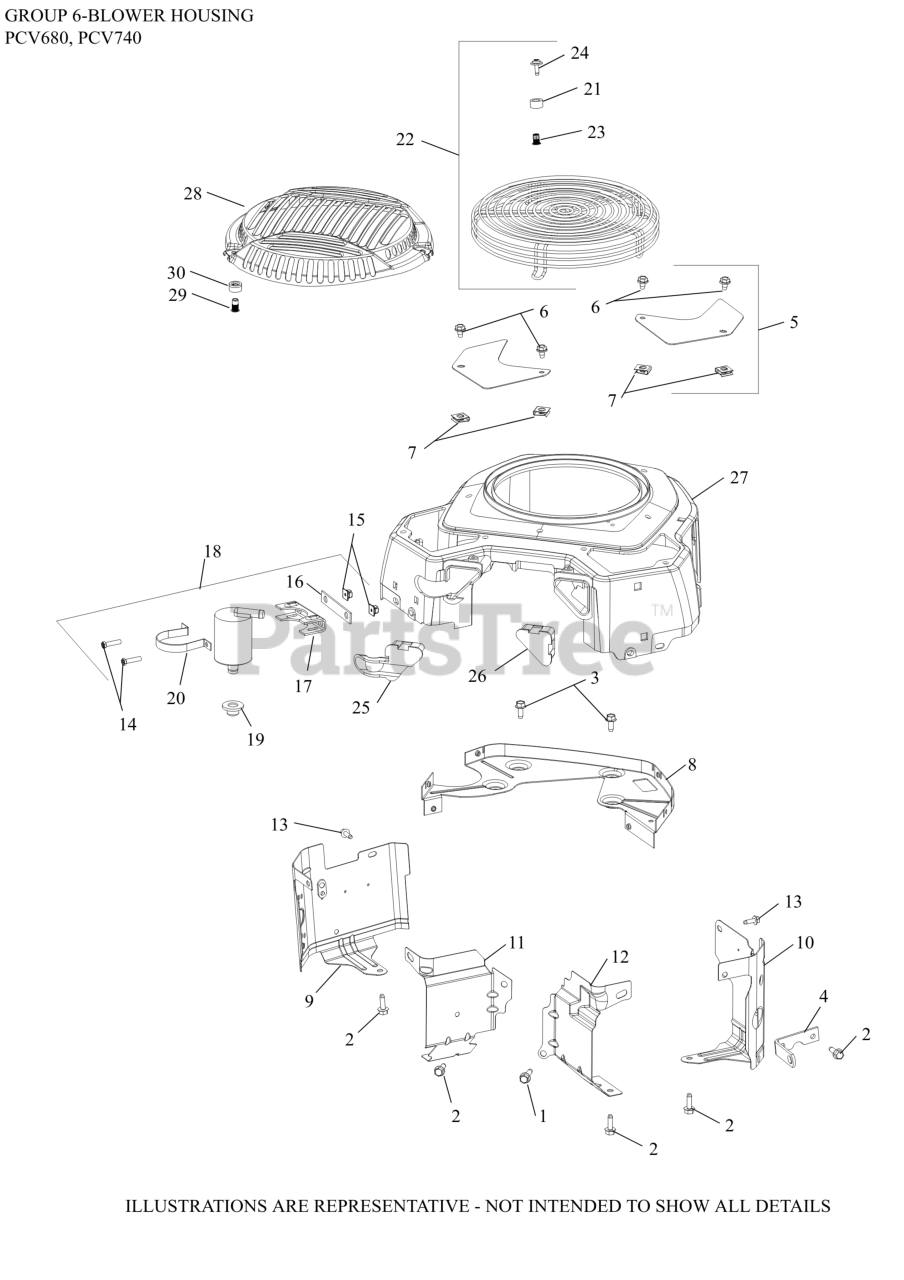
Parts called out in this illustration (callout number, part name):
1	SCREW, THREAD FORMING
2	SCREW, THREAD FORMING
3	SCREW, THREAD FORMING
4	STRAP, LIFT
5	COVER, ACCESS
5	KIT, ACCESS PANEL
6	SCREW, THREAD FORMING
7	CLIP, BAFFLE MOUNTING
8	PLATE, BACKING
8	KIT, BACKING PLATE
9	KIT, RIGHT BARREL
10	BAFFLE LEFT BARREL
11	BAFFLE, VALLEY #1 CYL-USE 24 063 114-S
12	BAFFLE, VALLEY #2 CYLINDER
13	SCREW, THREAD FORMING
24	SCREW, SEMS
25	COVER, BLOWER HOUSING
26	COVER, BLOWER HOUSING
27	KIT, BLOWER HOUSING
28	GUARD, GRASS SCREEN (METAL)
29	INSERT, THREADED (M5)
